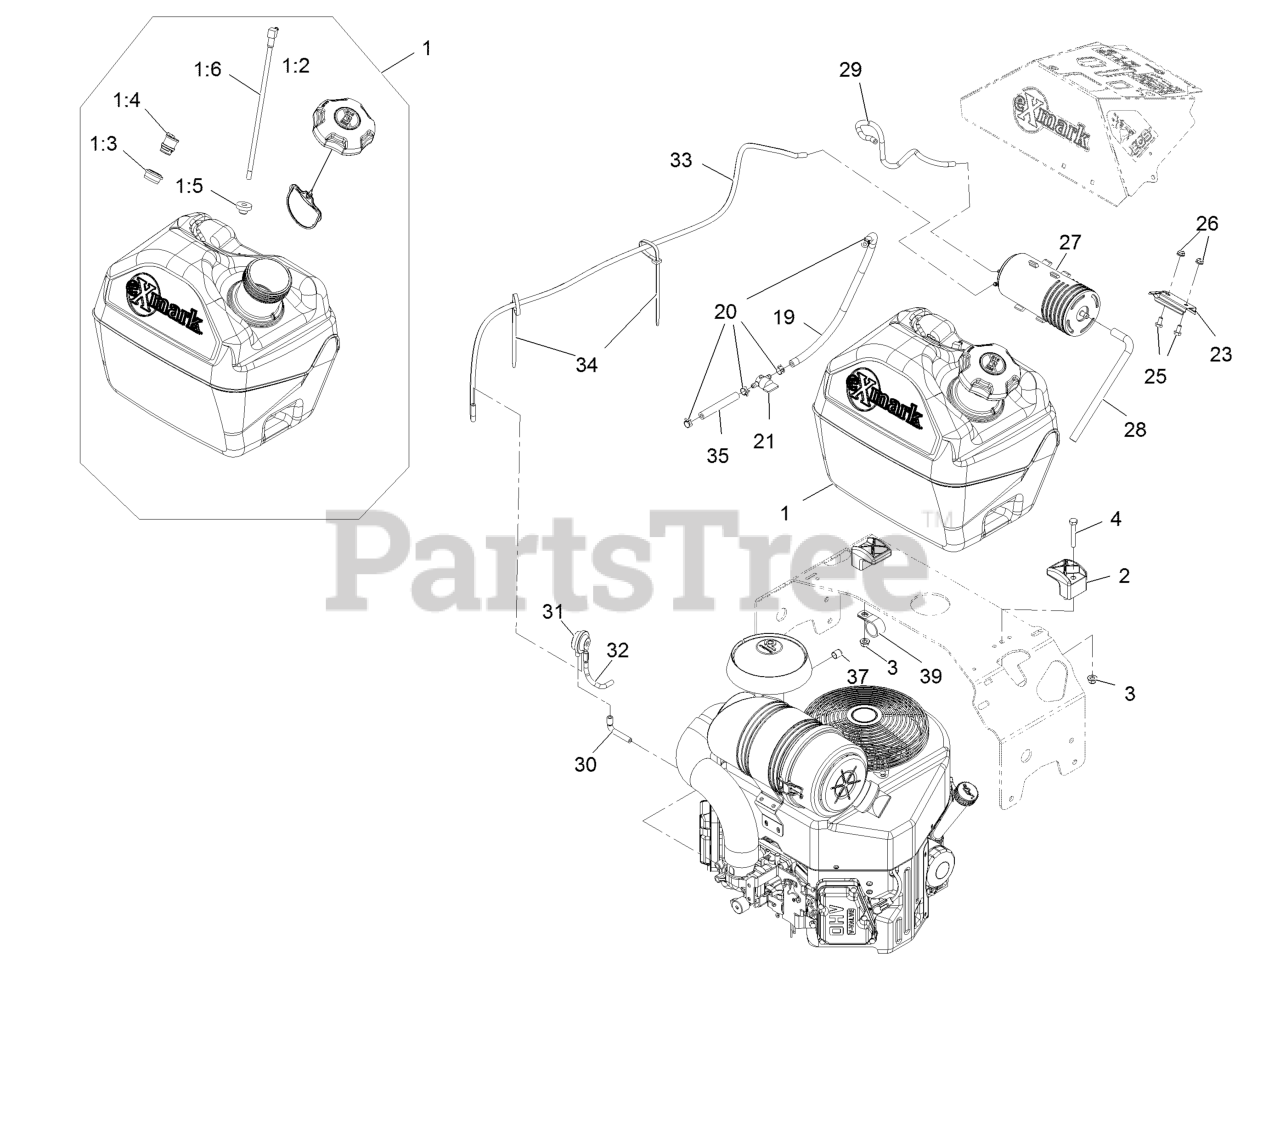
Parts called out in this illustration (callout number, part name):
1	ASM, Fuel Tank 5 Gal
1:2	Cap-Fuel, Ratcheting
1:3	Grommet
1:4	Valve-Vent, Fuel
1:5	Bushing
1:6	Fitting-Fuel (W/Line And Screen)
3	Nut-Nyloc 5/16-18 Flg
4	Screw-HH 5/16-18 X 2
19	Hose-Fuel
20	Clamp-Hose
21	Valve-Fuel
23	Bracket-Canister, Carbon
25	Screw-HH 1/4-20 X 1/2
26	Nut-Nyloc 1/4-20 Flg
27	Canister-Carbon, 800Cc
28	Hose-Vent, Canister
29	Hose-Emissions
30	Hose-Vent, Formed
31	Valve-Control, Vacuum
32	Hose-Vent, Formed
33	Hose-Vent, Formed
34	Tie-Cable 7 15/16 (Large)
35	Hose-Fuel
37	Plug-Port
39	Clip-Loom
